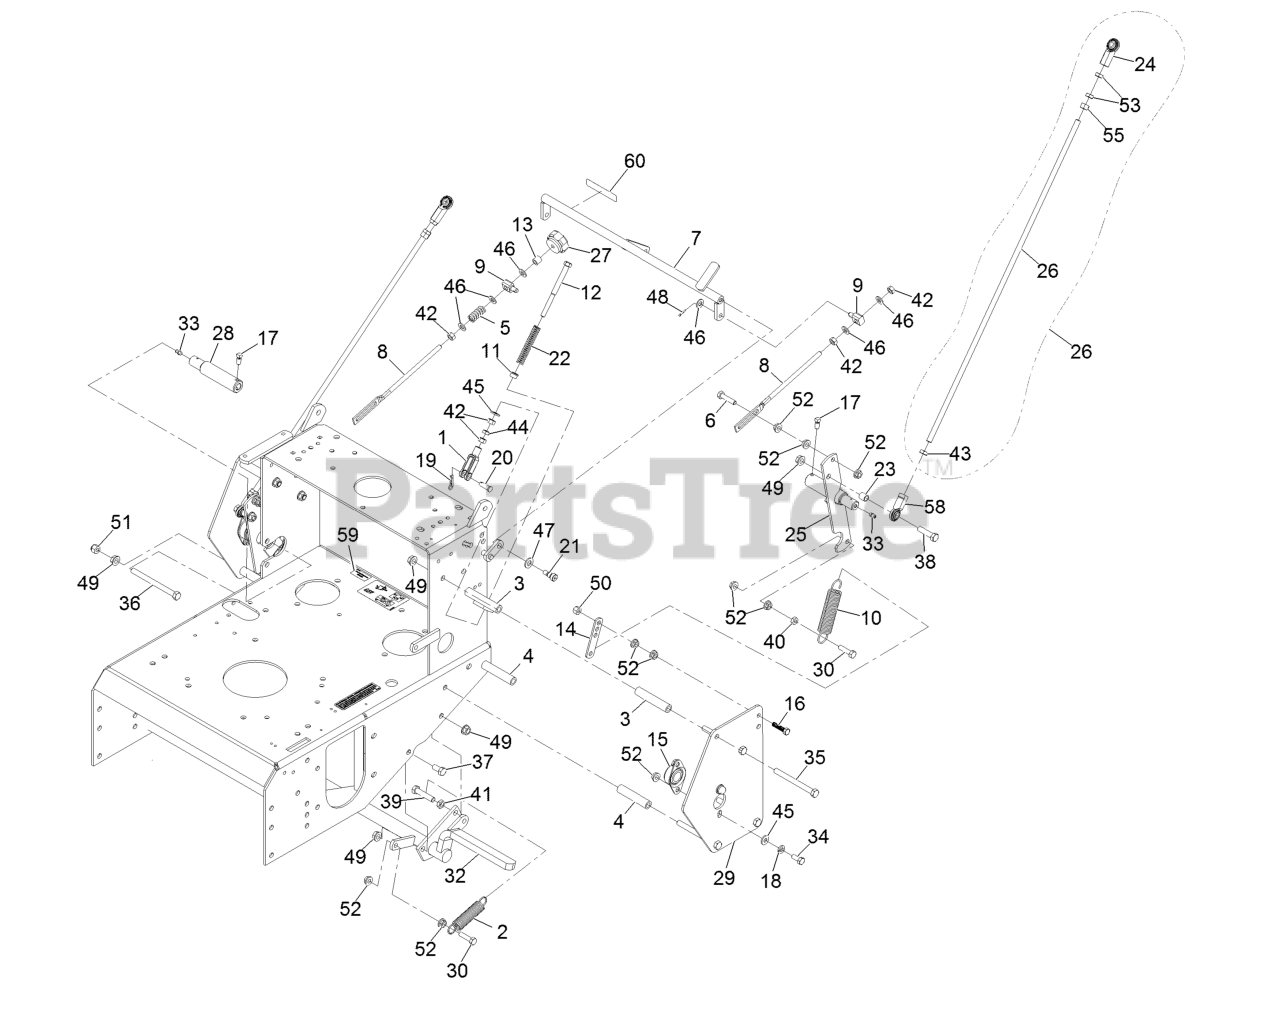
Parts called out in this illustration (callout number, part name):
1	Yoke-Adjustable
3	Spacer-Shield
4	Spacer-Shield
5	Spring-Compression
6	Screw-HH 5/16-18 X 1 3/8 Special
7	Crank-Control, Speed
8	Link-Control, Speed
9	Swivel-Adjustable, Short
11	Bushing-Flanged
12	Bolt-Neutral Return
14	Tab-Spring, Extension
15	Bearing-Flanged
16	Bolt-HH 5/16-18 X 1 1/4 Tap
17	Setscrew-5/16-18 X 5/8
18	Washer-Lock 5/16 Heavy
19	Hairpin-Cotter
20	Pin-Clevis 5/16 X 1 49/64
21	Screw-Sh 5/16-18 X 1 3/8
22	Spring, Neutral Return
23	Spacer-Tube, Pump Link
24	Balljoint
25	Shaft-Control, LH
26	Linkage, Drive
26	Drive Link ASM
27	Knob-Tracking
28	Shaft-Control, RH
29	Shield-Control
30	Screw,HH Special 5/16-18 X 1.25
33	Zerk-1/4-28 Str
34	Screw-HH 5/16-18 X 3/4
35	Screw-HH 3/8-16 X 4
36	Screw-HH 3/8-16 X 4-1/2
37	Screw-HH 3/8-16 X 3/4
38	Screw-HH 3/8-16 X 1 1/2
39	Screw-HH 3/8-16 X 1 3/4
40	Nut-Jam 5/16-18
41	Nut-Jam 3/8-16
42	Nut-Hex 5/16-24
43	Nut-Jam 3/8-24 LH
44	Nut-Jam 5/16-24
45	Washer-1/4 Std
46	Washer-5/16 SAE
47	Washer-3/8 SAE
48	Pin-Cotter 3/32 X 1/2
49	Nut-Whizlock 3/8-16
50	Nut-Nyloc 5/16-18
51	Nut-Nyloc 3/8-16
52	Nut-Whizlock 5/16-18
53	Nut-Jam 3/8-24
55	Nut-Hex 3/8-24
58	Joint-Ball End
59	Decal-Patent
60	Decal-Tracking Adjustment
